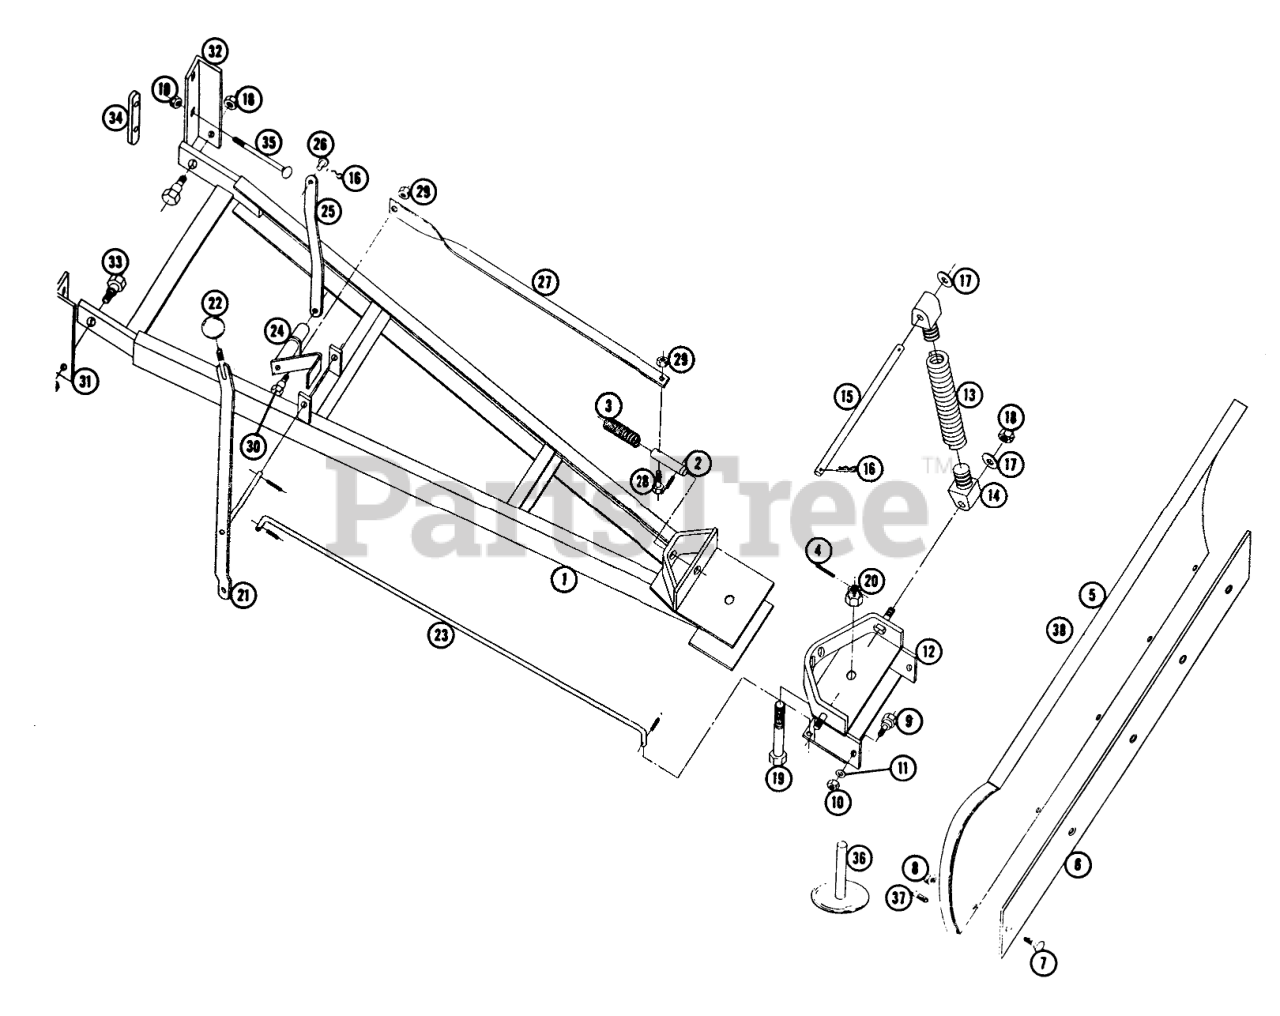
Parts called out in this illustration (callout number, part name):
1	Frame W/A
2	Index Pin
3	SPRING-COMPRESSION
4	Cotter Pin
5	Ass-y. Blade W/A
6	Plate
7	Bolt Hex 5/16-18 x 3/4
8	Nut-Nylok
9	Bolt-Shoulder
11	Washer
12	Ass-y. Sector W/A
13	Spring
14	Lug
15	ROD-PIVOT, BLADE
16	Hairpin
17	Washer
18	Locknut-1/2-13
19	Bolt-Hex 3/4-16 x 3 3/4
20	Nut-Castle 3/4-16
21	Ass-y. Lever W/A
22	Knob
23	Pivot Rod
24	Foot Lever Ass-y.
25	Lift Bar
27	Bar-Trip
28	Cotter Pin
29	Nut-Nylok
30	Bolt-Shoulder
31	Bracket-R.H. Mtg.
32	Bracket-L.H. Mtg.
33	Bolt Shoulder
34	Link-Mtg. Bracket
35	Bolt-Carriage 3/8-16 x 3
36	Skid
37	Set Screw 3/8-16 x 5/8 Sq. HD.
38	Decal
